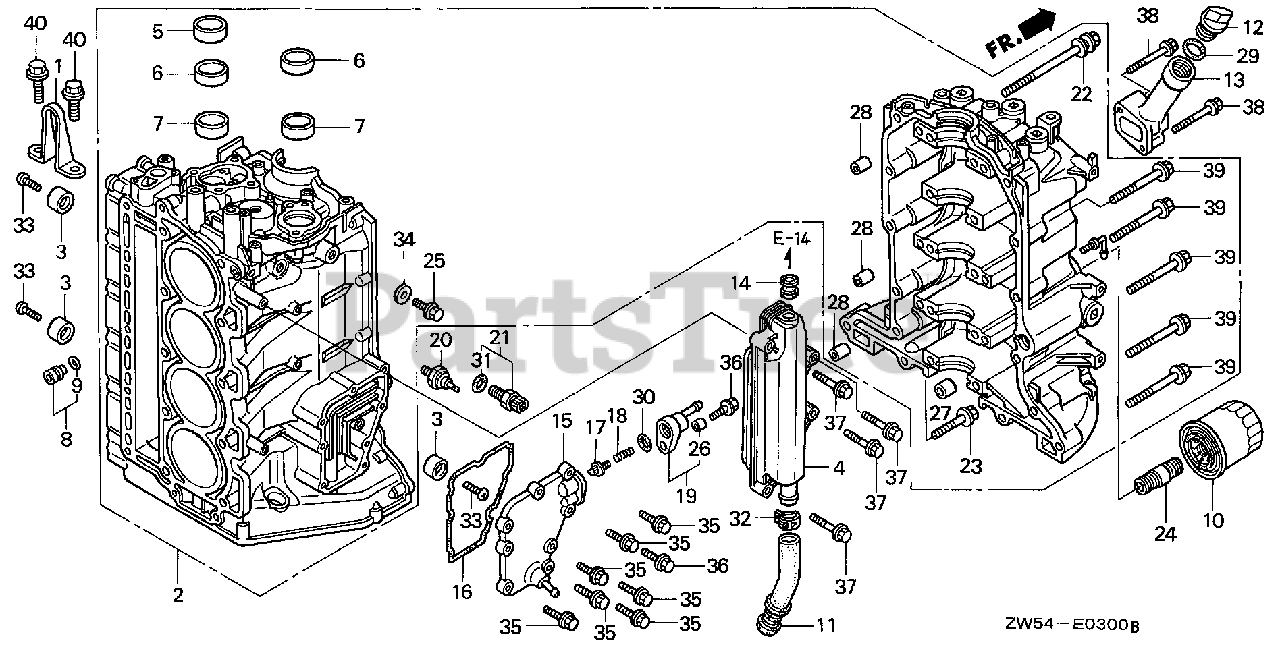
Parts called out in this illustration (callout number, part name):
1	HANGER, ENGINE
2	BLOCK ASSY., CYLINDER *NH8* (DARK GRAY)
3	METAL, ANODE
4	CHAMBER, PCV
5	METAL, BALANCER SHAFT (NO.1) (DAIDO)
6	METAL, BALANCER SHAFT (NO.2) (DAIDO)
7	METAL, BALANCER SHAFT (NO.3) (DAIDO)
8	ORIFICE ASSY., OIL CONTROL
9	O-RING (10.8X2.4) (ARAI)
10	FILTER, OIL (FILTECH TOYO ROKI) (SOLD INDIVIDUALLY)
10	FILTER, OIL (TOYO ROKI) (SOLD INDIVIDUALLY)
10	FILTER, OIL (SOLD INDIVIDUALLY)
11	TUBE SET, OIL
12	CAP, OIL (YELLOW)
13	EXTENSION, OIL FILLER *NH8* (DARK GRAY)
14	GROMMET, PCV VALVE
15	COVER, OIL WATER JACKET *NH8* (DARK GRAY)
16	GASKET, OIL WATER JACKET COVER
17	VALVE, OIL WATER JACKET PRESSURE
18	SPRING, OIL WATER JACKET PRESSURE VALVE
19	HOLDER, OIL WATER JACKET PRESSURE VALVE
20	SWITCH ASSY., OIL PRESSURE
21	SENSOR ASSY., WATER TEMPERATURE
22	BOLT-WASHER (11X131)
23	BOLT, FLANGE (10X40)
24	HOLDER, OIL FILTER
25	BOLT, DRAIN PLUG (12MM)
26	COLLAR (6MM)
27	PIN, DOWEL (18X22)
28	PIN, DOWEL (13X20)
29	O-RING (26X2.7)
30	O-RING (16.5X2.5)
31	O-RING (9.5X1.5) (HONDA KIKAKI)
32	CLAMP, TUBE (D29)
33	SCREW, PAN (6X18)
34	WASHER, DRAIN PLUG (12MM)
35	BOLT, FLANGE (6X20)
36	BOLT, FLANGE (6X25)
37	BOLT, FLANGE (6X35)
38	BOLT, FLANGE (6X40)
39	BOLT, FLANGE (10X55)
40	BOLT, FLANGE (12X30)
